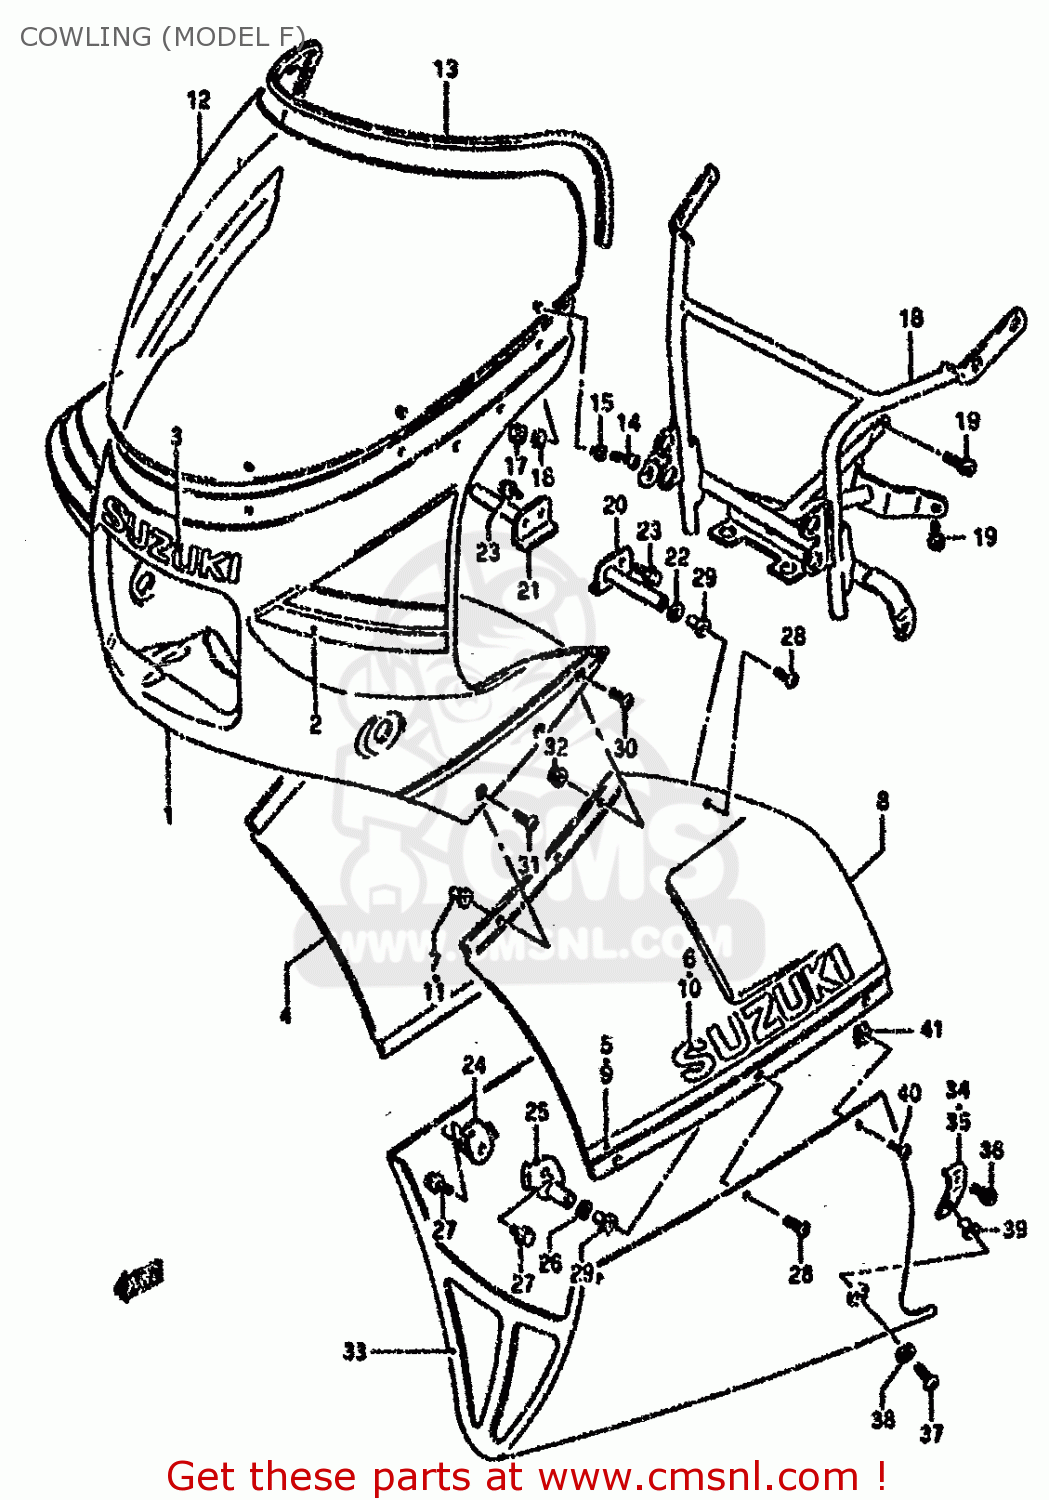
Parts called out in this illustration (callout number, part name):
1	BODY,COWLING (RED
2	TAPE SET,COWLING
3	EMBLEM,HEADLAMP
4	COVER,SIDE RH (WHITE)
5	TAPE SET,SIDE RH (BLUE)
6	EMBLEM
7	NUT,COWLING COVER
8	COVER,SIDE LH (WHITE)
9	TAPE SET,SIDE LH (BLUE)
10	EMBLEM
11	NUT,COWLING COVER
12	WIND SCREE,COWLING
13	MOLDING, SCREEN
14	SCREW(5X14)
15	CUSHION
16	WASHER,5MM
17	NUT 8MM
18	BRACE,COWLING
19	BOLT
20	BRACE,COWLING RR
21	BRACE,REAR RH
22	WASHER (10.5X18X1)
23	BOLT
24	BRACE,SIDE RH
25	BRACE,SIDE LH
26	WASHER (10.5X18X1)
27	BOLT 6X16
28	SCREW
29	NUT
30	SCREW 6X12
31	SCREW
32	NUT 6MM
33	COVER,LOEWR (WHITE/RED)
34	BRACE,COWLING LWR COVER
35	BRACE,COWLING LWR COVER,R
36	BOLT 6X16
37	SCREW
38	WASHER
39	NUT
40	SCREW
41	NUT
